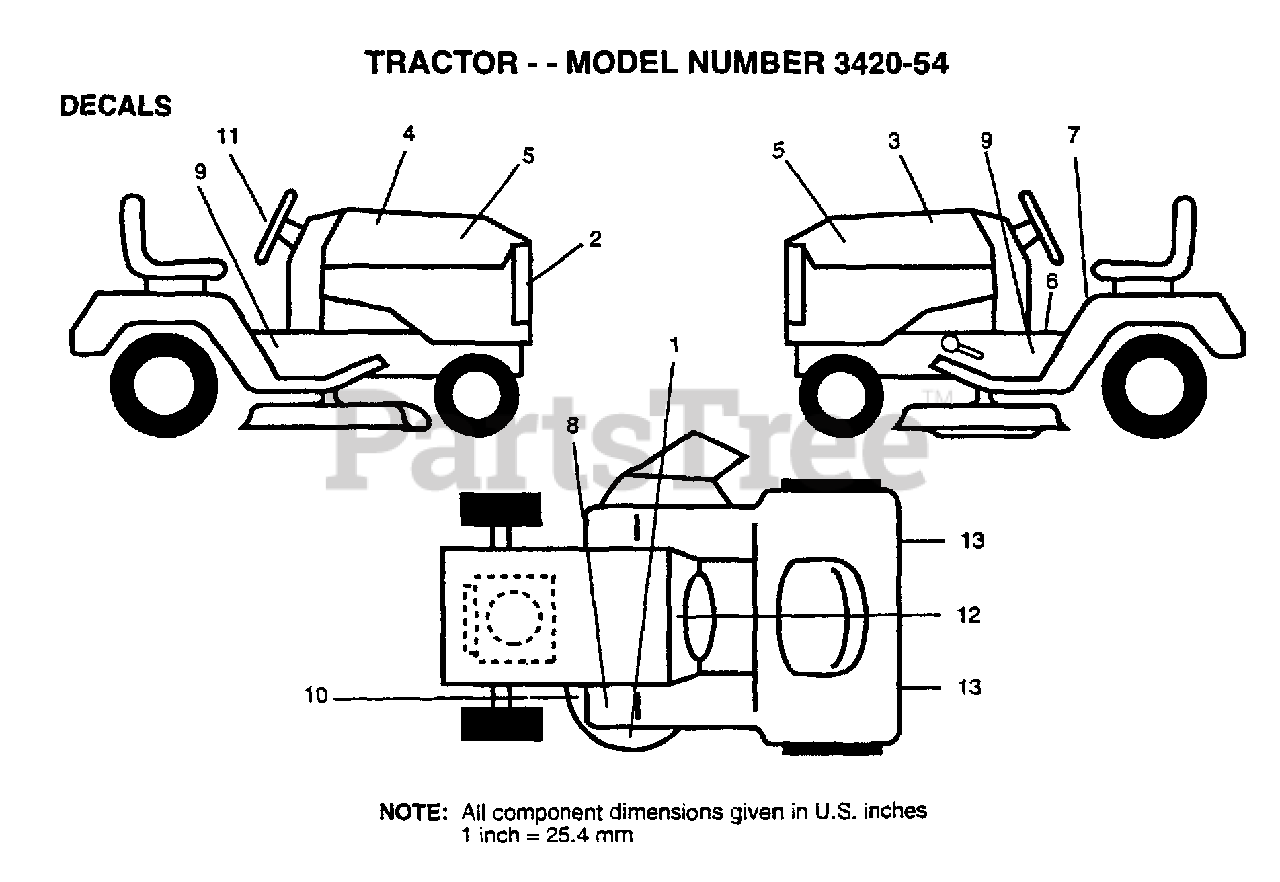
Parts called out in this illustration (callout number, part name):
2	GRILL DECAL
3	HOOD DECAL LH
5	NAMEPLATE LOGO
6	DECAL BRAK PARK
7	DECAL
9	DECAL CHASSIS
10	DECAL
12	DECAL.DASH.INST.
13	REFLECTOR-TAIL YT
